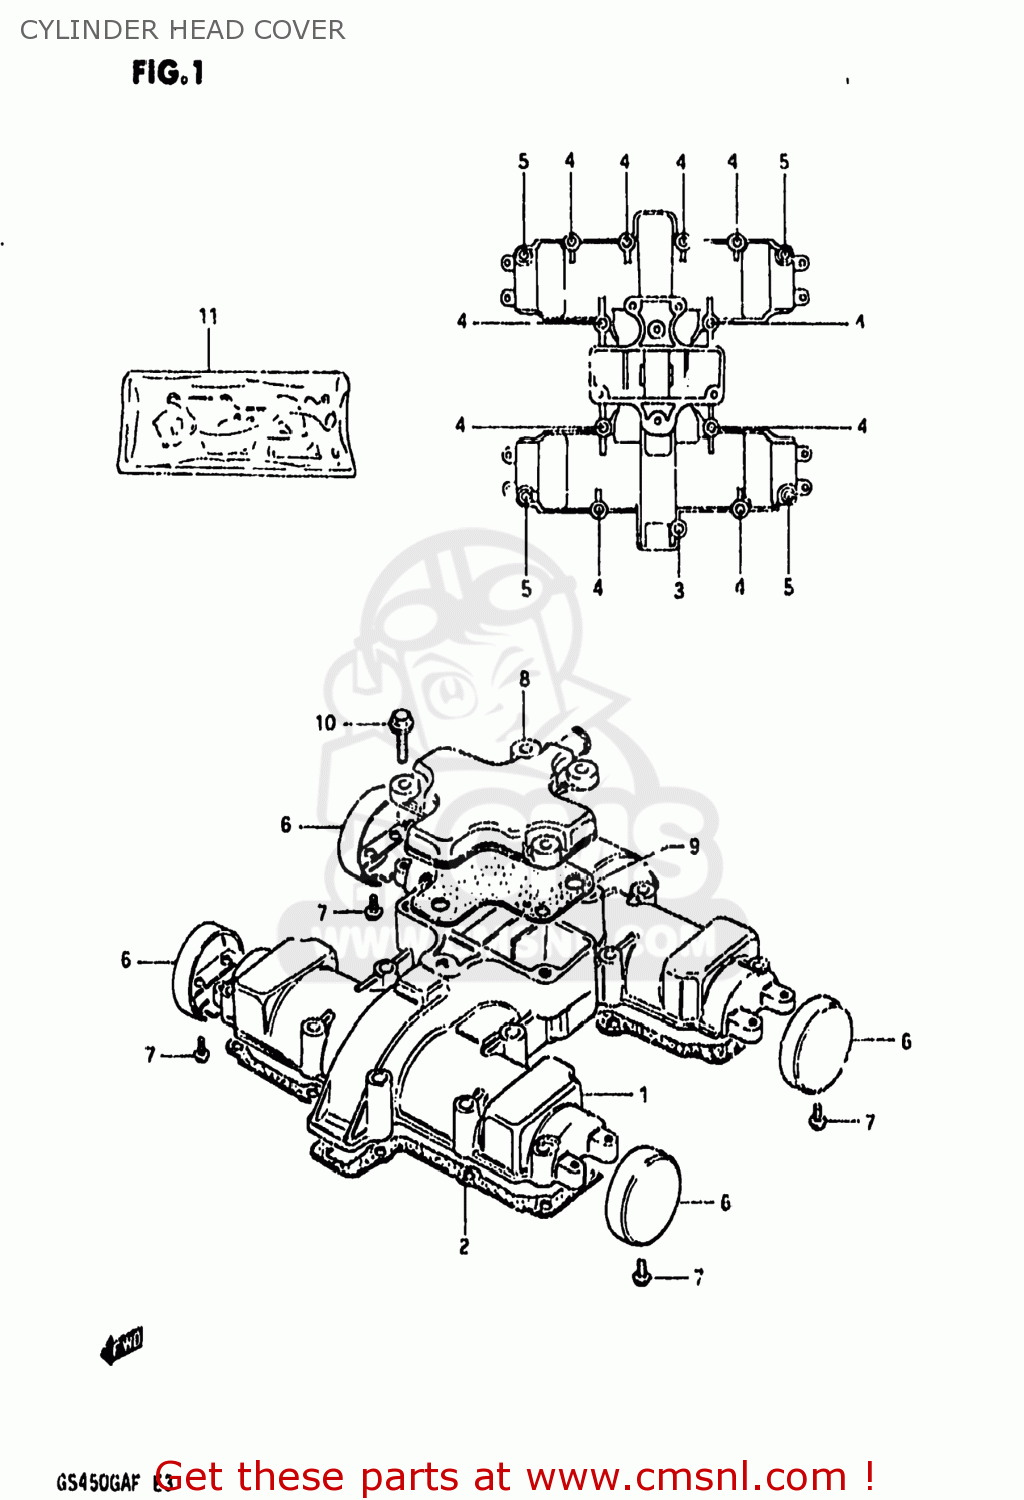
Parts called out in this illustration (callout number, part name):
1	COVER,CYLINDER HEAD
2	GASKET,CYLINDER HEAD COVER (MCA)
3	BOLT (6X45)
4	BOLT
5	BOLT 6X30
6	CAP,CYLINDER HEAD COVER
7	SCREW
8	COVER,BREATHER
9	GASKET (MCA)
10	BOLT
11	GASKET SET,ENGINE
